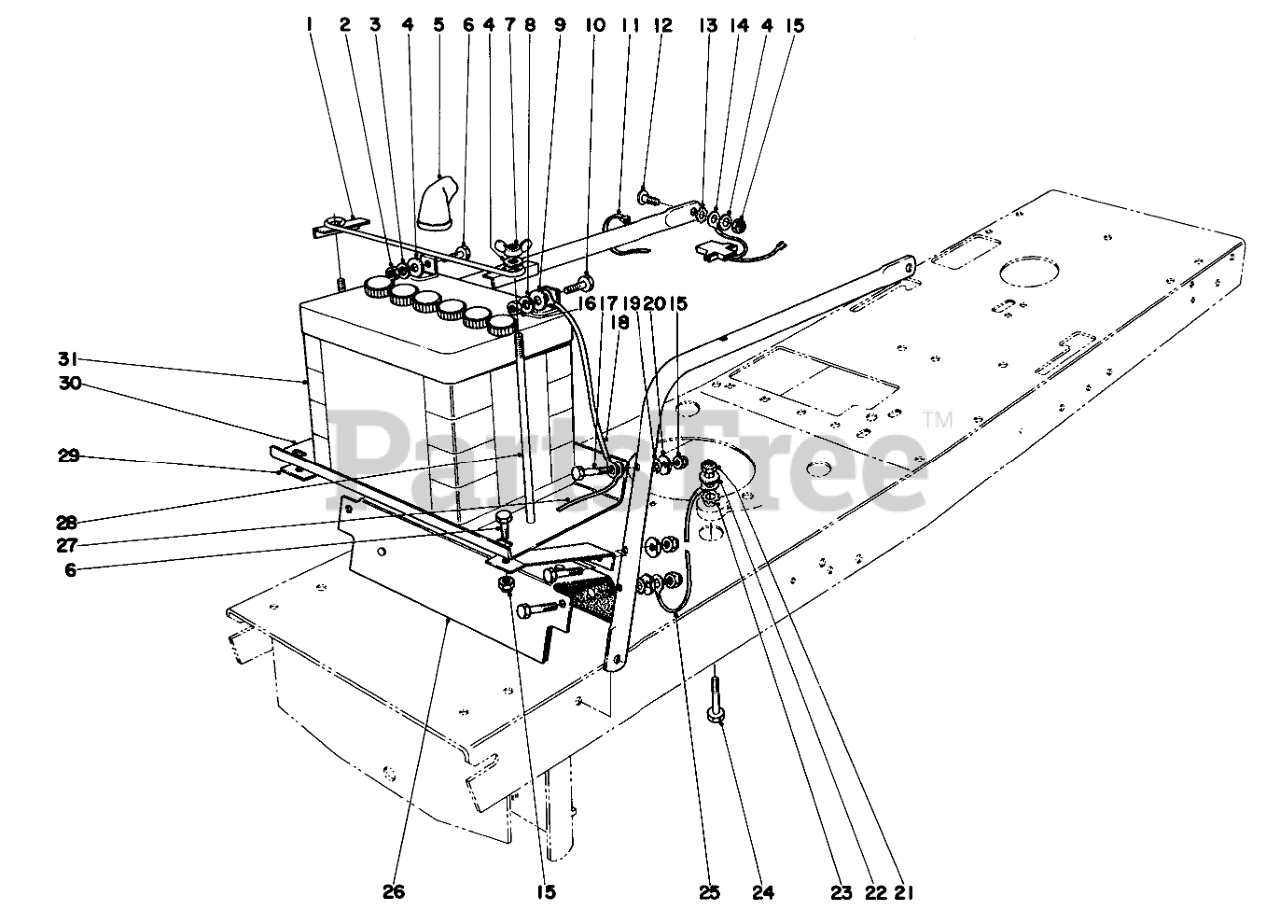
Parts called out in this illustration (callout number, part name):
1	Battery Clamp
2	NUT-HEX
3	WASHER-LOCK
4	WASHER-FLAT
5	BATTERY BOOT
6	SCREW-HH
7	WING NUT
8	WASHER-LOCK
9	WASHER-PLAIN
10	SCREW-HH
11	Cable Tie
12	BOLT-CARR
13	WASHER-LOCK/EXT
14	Wire Assembly
15	NUT-LOCK, CONE
16	NUT-HEX
17	SCREW-HH
18	Wire Assy. Battery to Ground
19	WASHER-LOCK/EXT
20	WASHER
21	NUT-LOCK, CONE
22	WASHER-PLAIN
23	WASHER-LOCK
24	SCREW-HH
25	Wire Assy. Engine to Ground
26	Heat Shield
27	Wire Assembly Headlight to Ground
28	BATTERY BOLT
29	Brace Battery Shelf
30	Battery Shelf
31	Battery
